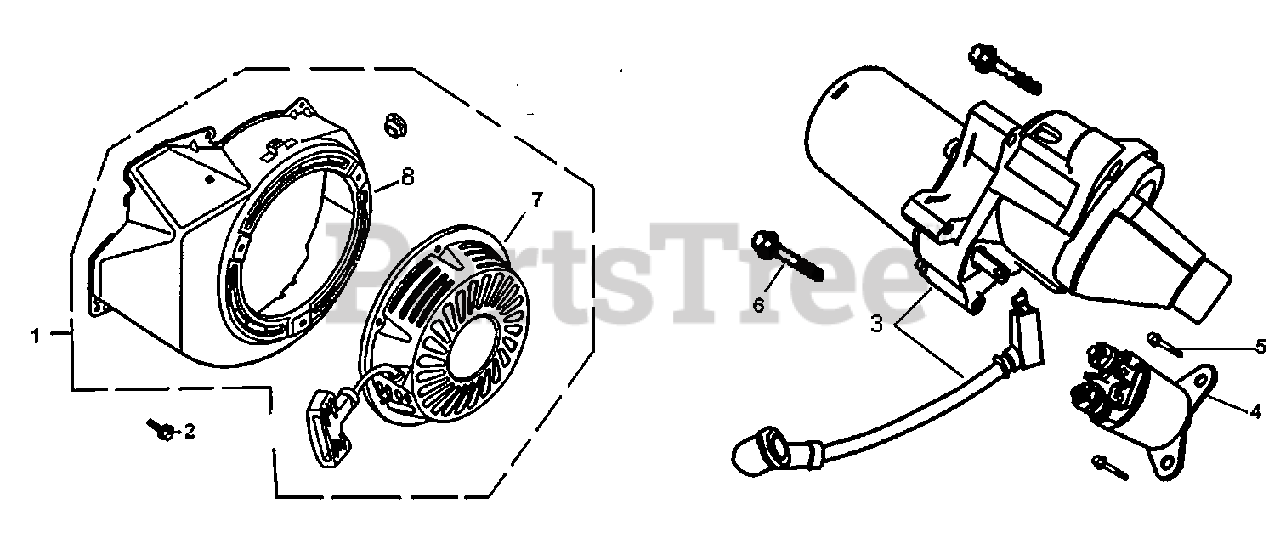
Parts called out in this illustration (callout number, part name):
1	STARTER ASSY.
2	BOLT, FLANGE, M6X12
3	STARTER MOTOR
4	CONTACTOR ASSY.
5	BOLT-WASHER, M6X14
6	BOLT, FLANGE,M8X35
